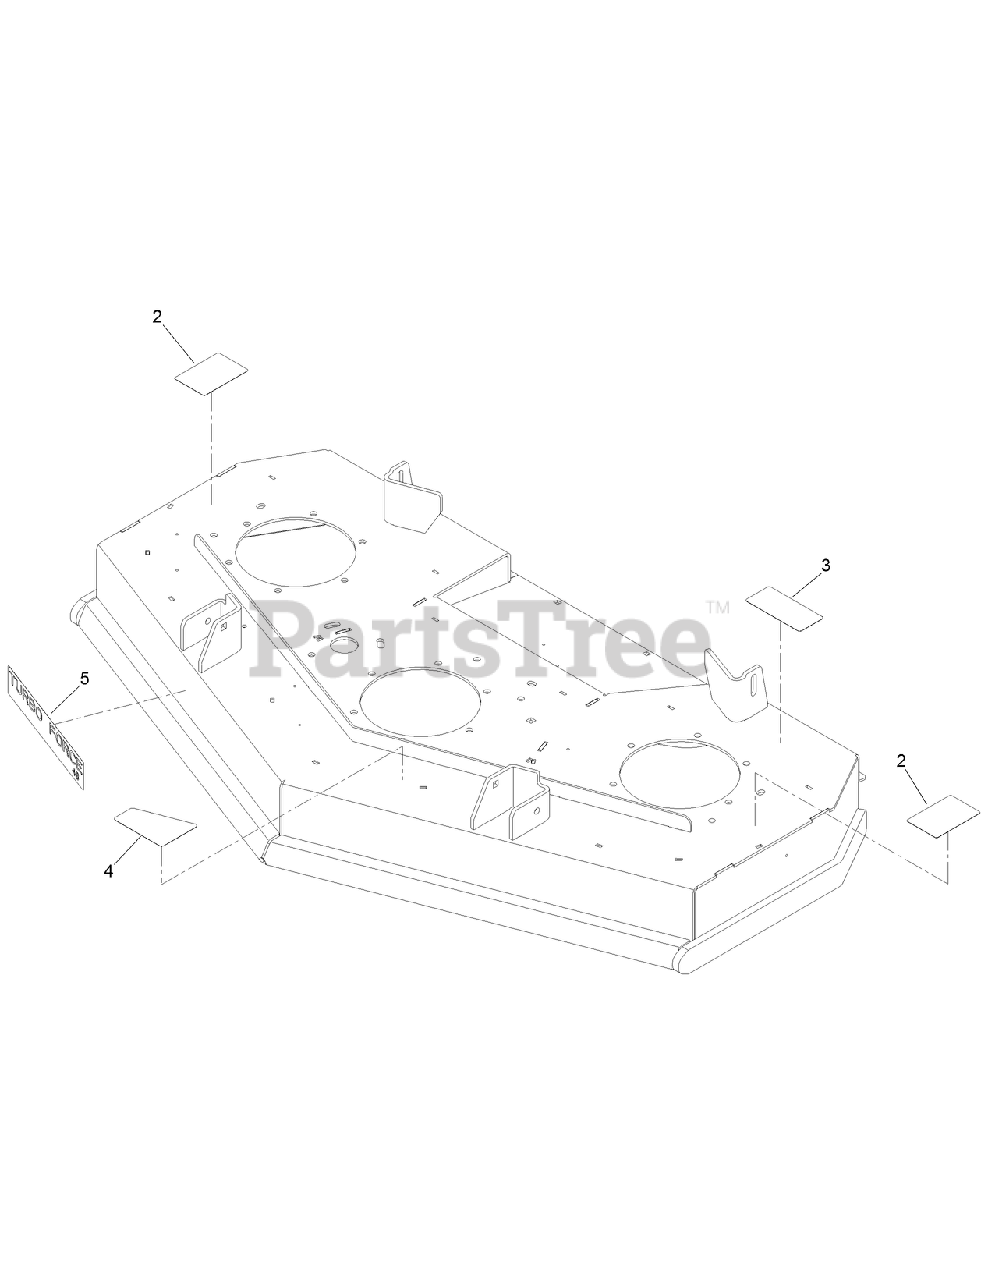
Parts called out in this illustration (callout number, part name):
2	DECAL-DANGER, CE
3	DECAL-TORQUE, BLADE BOLT
4	DECAL-BELT, TENSION (CE)
